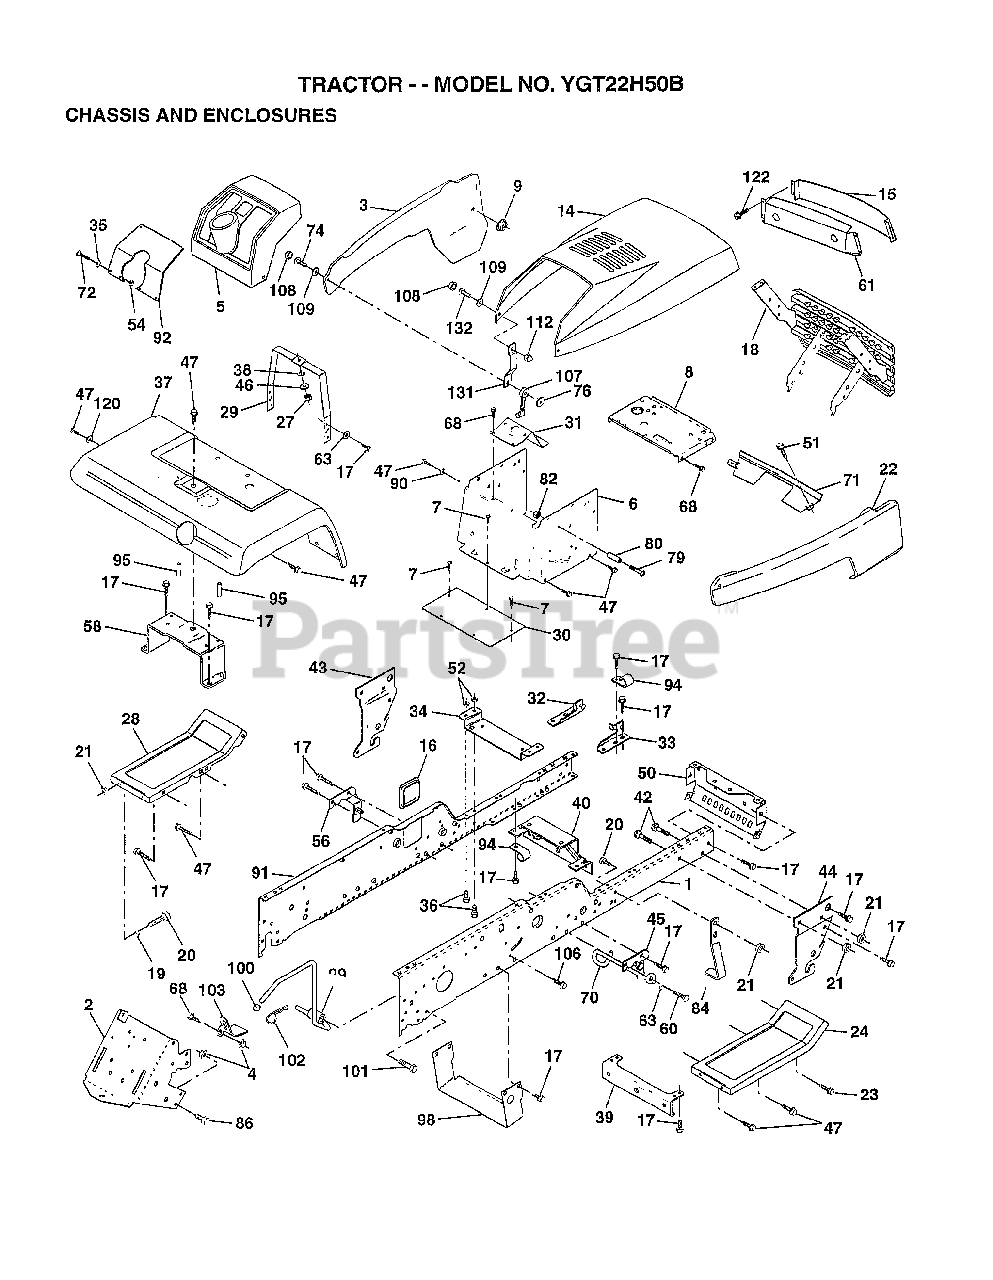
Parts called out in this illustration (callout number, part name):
1	"RAIL,FRAME RH"
2	DRAWBAR GT
3	"PANEL ASM-SIDE,LH"
4	NUT.7/16
5	DASHBOARD BLACK
6	DASH LOWER
7	SCREW
8	SUPPORT.DASH.BTRY
9	PAL NUT LT
14	"HOOD, YARD PRO"
15	LENS.BAR.CLEAR
16	COVER ACCESS
17	SCREW
19	WASHER
20	BOLT
22	"PANEL ASM SIDE,RH"
23	SCREW GTV
24	FOOTREST.RH.LT/GT
28	FOOTREST PNT LH
29	DASH.SUPT.YP/HUSQ
30	SADDLE.HYDRO.95
31	BRKT SUPT 1-PC VG
32	BRACKET ASM FRAME
33	BRACKET ASM FRAME
34	BRACKET.ENG.SUPT.
35	WASHER
36	BOLT
37	"FENDER WS,FTK"
38	LOCKWASHER
39	BRACKET.AXLE.FRT.
40	"BRKT SUPPORT,AXLE"
43	BRACKET.SUS.FT.LH
44	BRACKET.SUS.FT.RH
45	BRACKET.SUSP.RH.
46	WASHER PM
47	SCREW LT
50	"BRKT CHASSIS,FRNT"
56	BRACKET.SUSP.LH.
58	BRKT.ASM.FENDER
60	SCREW
61	BEZEL.1 PC
63	WASHER
70	GUIDE.BELT.MID.SP
72	SCREW
74	SCREW
76	WELDNUT
79	SCREW
80	SPACER LT
84	STOP.OVER.CENTER
86	BOLT
90	LOCKWASHER
91	"RAIL FRAME,LH"
92	"PLATE DASH,SLKSCR"
95	NUT-PUSH YT
98	BRACKET SKID CHAS
99	ROD BYPASS
101	SCREW LT
103	LOCK BYPASS BRKT
107	HOOD LATCH T
108	SNAP CAP LT
109	WASHER LT
112	ACORN NUT RB
120	WASHER HYT
122	SCREW.HEX.WS.HD
131	BKT.SPT.HOOD/PANL
132	SCREW.10-24X3/8.
